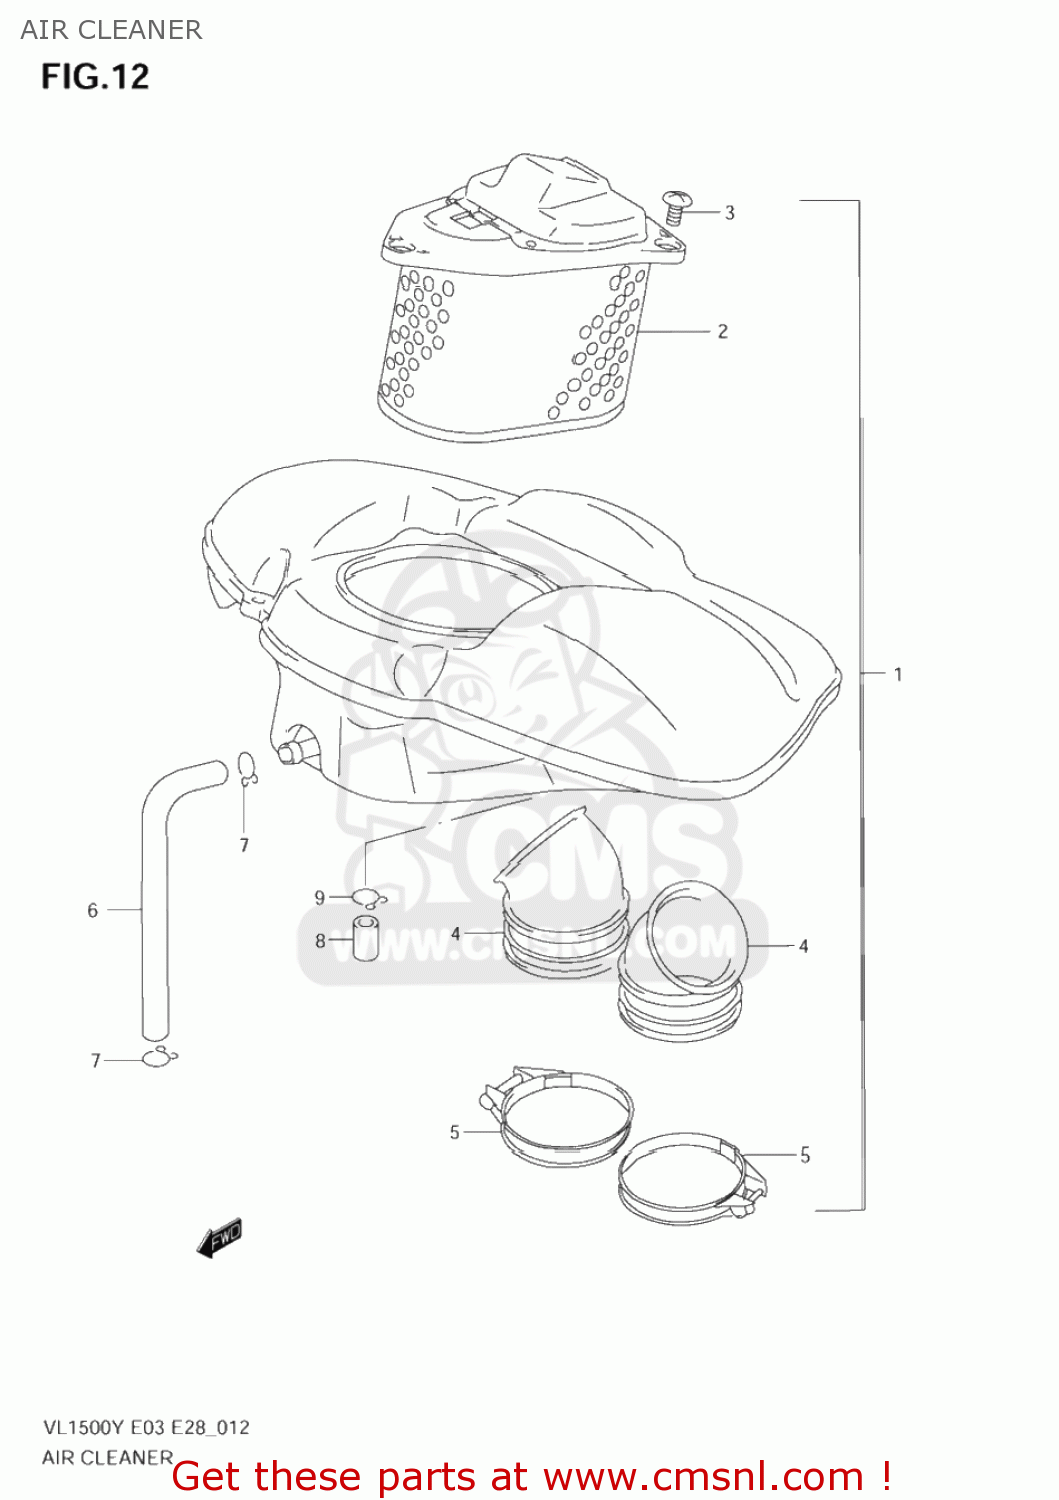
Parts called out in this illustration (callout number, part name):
1	CLEANER ASSY,AIR
2	FILTER,AIR CLEANER
3	SCREW 5X12
4	TUBE,OUTLET
5	CLAMP
6	TUBE,BREATHER
7	CLIP
8	PLUG
9	CLIP
